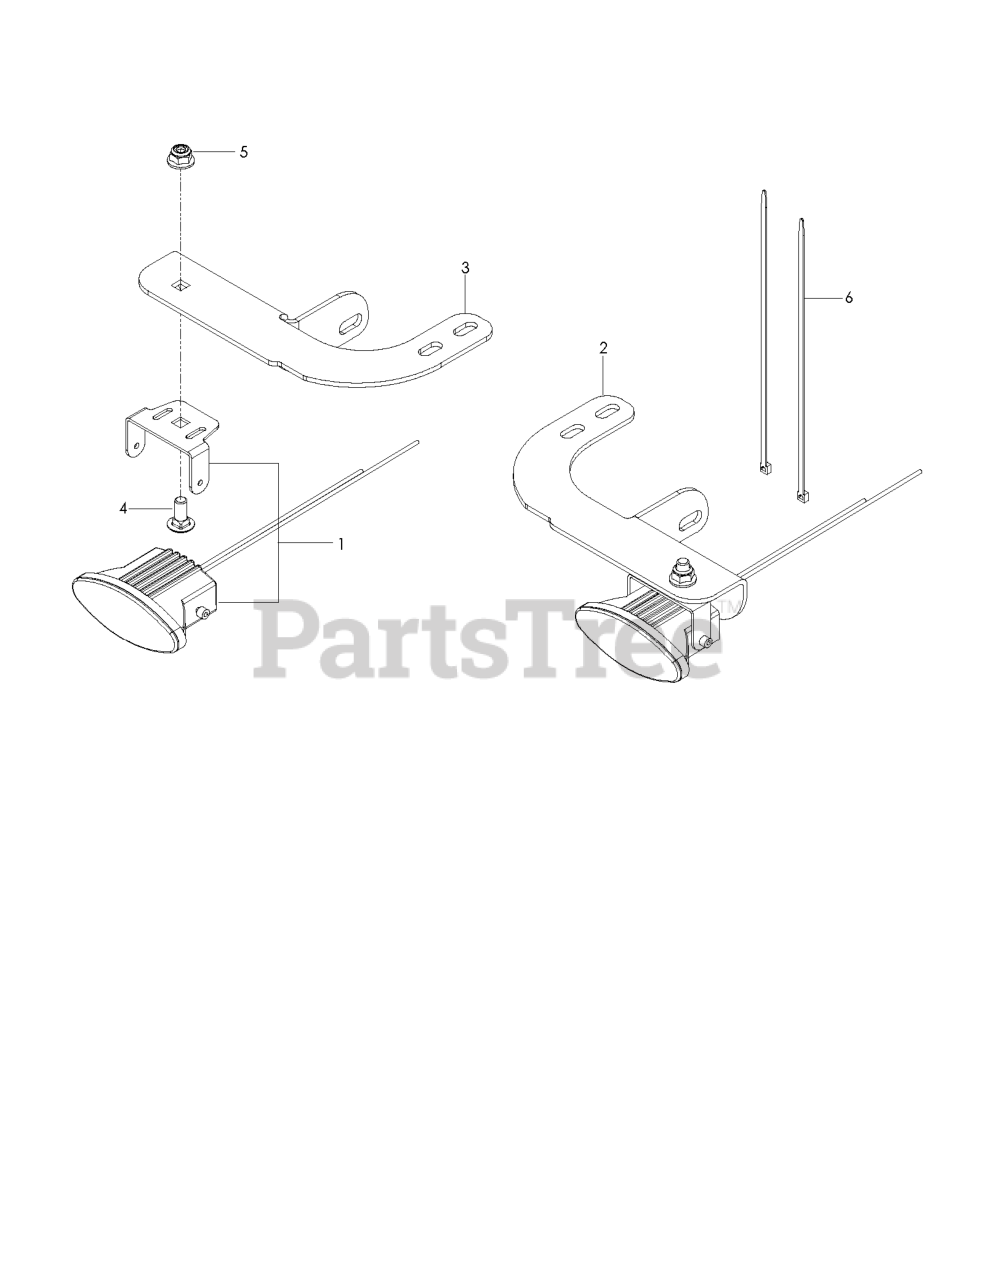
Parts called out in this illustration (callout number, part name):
1	LIGHT 35W W/BRKT
2	BRKT, LIGHT, LT, BLK
3	BRKT, LIGHT, RT, BLK
4	BOLT 5/16C X 3/4" CARRIAGE
5	5/16-18 NYLOC FLANGE NUT
6	TIE, PLASTIC
